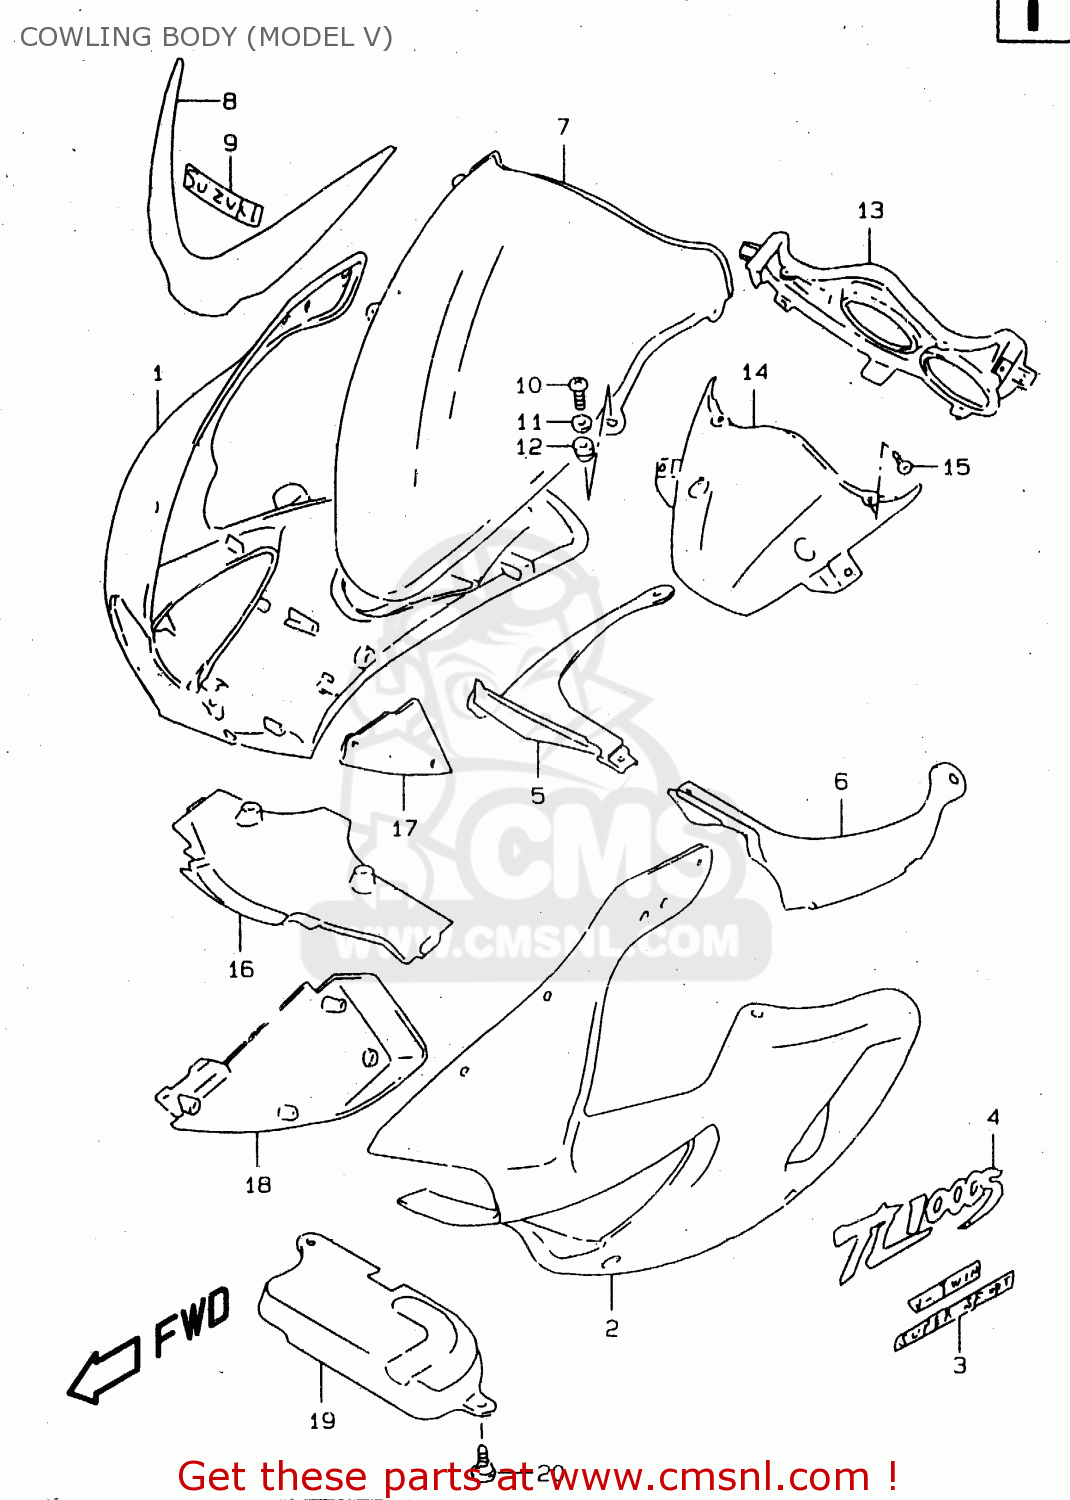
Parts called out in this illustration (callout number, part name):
1	COWLING,SIDE,R(RED)
2	COWLING,SIDE,L(RED)
3	EMBLEM,COWLING SIDE
4	EMBLEM,COWLING SIDE,TL1000S
5	PANEL,SIDE,R
6	PANEL,SIDE,L
7	WINDSCREEN(SILVER)
8	TAPE,WINDSCREEN
9	EMBLEM(SILVER)
10	SCREW(5X14)
11	WASHER
12	NUT
13	PANEL,METER
14	PANEL,FR
15	CLIP(BLACK)
16	COWLING,CTR LWR
17	COWLING,INNER,R
18	COWLING,INNER,L
19	COVER,COWLING FR LWR
20	BOLT
